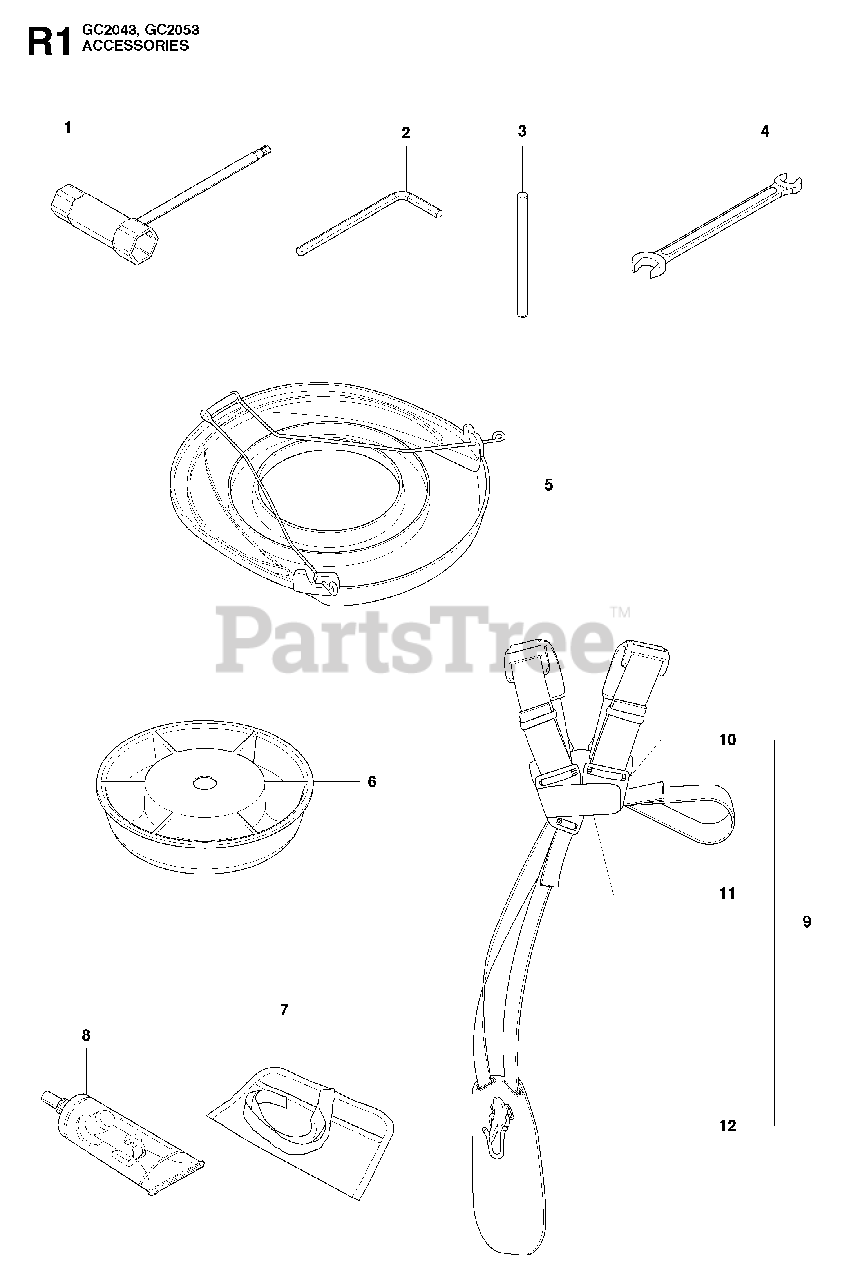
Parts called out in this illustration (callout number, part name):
5	TRANSPORT GUARD
6	SUPPORTING CUP
10	FRONT PIECE
11	FRONTPIECE-RIGHT NLA
12	HOOK, CPL.
